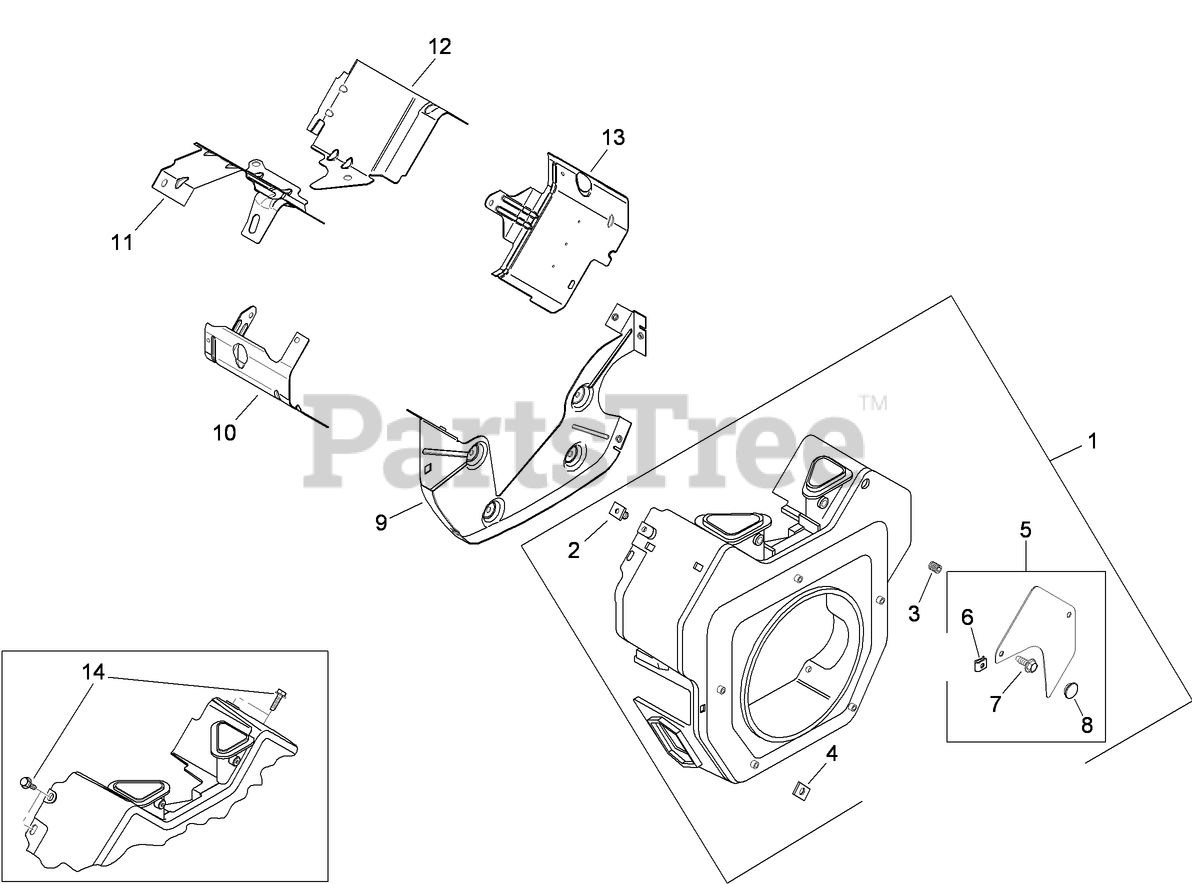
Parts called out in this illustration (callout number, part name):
1	Housing-Blower (INCLUDES 2-8)
2	NUT-PLASTIC
3	Screw-Set (10-24X.25)
4	NUT-PLASTIC (BLACK)
5	Access Cover Kit (INCLUDES 6-8)
6	Clip-Mounting
7	SCREW-FLANGE, THREAD FORMING (M6X1.0X16)
8	PLUG-BUTTON (9/16)
9	PLATE-BACKING
10	BAFFLE-BARREL, CYLINDER (No. 2 SIDE)
11	BAFFLE-VALLEY (No.2 SIDE)
12	BAFFLE-VALLEY (No.1 SIDE)
13	Baffle-Barrel, Cylinder (No. 1 Side)
14	SCREW-FLANGE, THREAD FORMING (M6X1.0X16)
